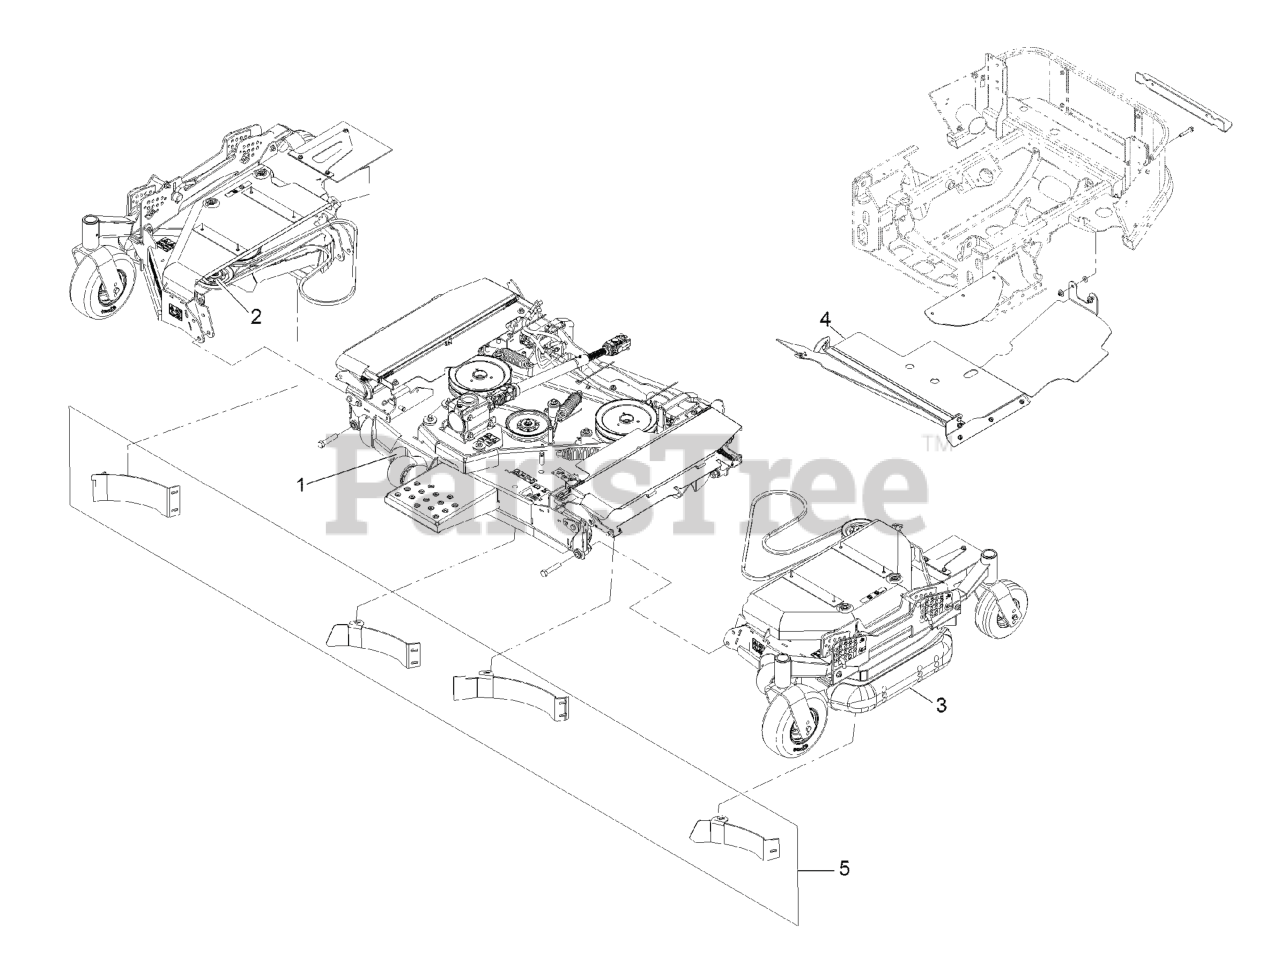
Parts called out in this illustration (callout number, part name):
1	ASM-DECK, CTR 96/120
2	ASM-DECK, RH WING 96
2	ASM-DECK, LH WING 96/120
4	Discharge Tunnel ASM
5	KIT-96RD MULCH
